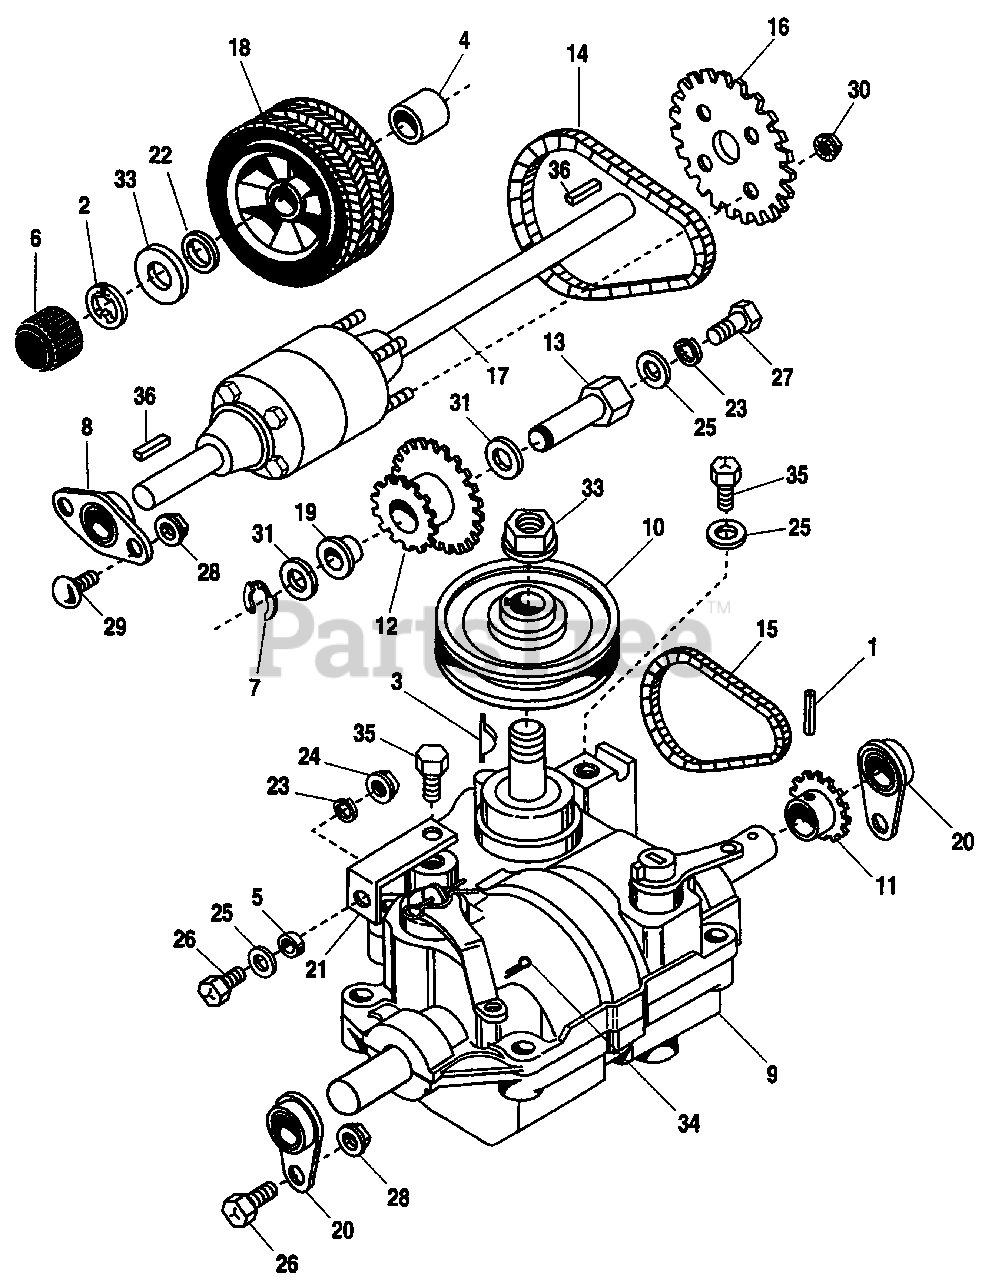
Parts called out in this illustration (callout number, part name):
1	PIN, Spring, 3/16 x 1
2	RETAINER RING, External "E" #75
3	KEY, Hi-Pro, 1/8 x 17/32
6	HUBCAP, Rear Wheel
7	KLIP RING, 3/8
8	BEARING, Flanged
9	TRANSMISSION (See pages 20-27 for service parts)
10	PULLEY ASSY.
11	SPROCKET, 10T
12	SPROCKET, Idler
13	SHAFT, Sprocket
14	CHAIN, 60 Pitch
15	CHAIN, 29 Pitch
16	SPROCKET, 54T
18	WHEEL, Rear, 10 x 3-1/2
19	BUSHING, Bronze, Flange, 3/8
20	BALL BUSHING ASSY.
21	STRAP, Torque
22	WASHER, 3/4
23	LOCKWASHER 5/16
24	NUT, Hex Hd., 5/16-18
25	WASHER, 5/16
26	CAPSCREW, Hex Hd, 5/16-18 x 3/4
27	CAPSCREW, 5/16-18 x 7/8
28	NUT, Hex, Flange Lock, 5/16-18
29	CARRIAGE BOLT, 5/16-18 x 3/4
30	NUT, Flange Lock, 5/16-18
31	WASHER, 3/8
32	WASHER, 3/4
33	NUT, Lock, M10
34	COTTER PIN, 7/64 x 3/4
35	SCREW, Taptite, 5/16-18 x 3/4
36	KEY, 3/16 sq. x 1-1/2
